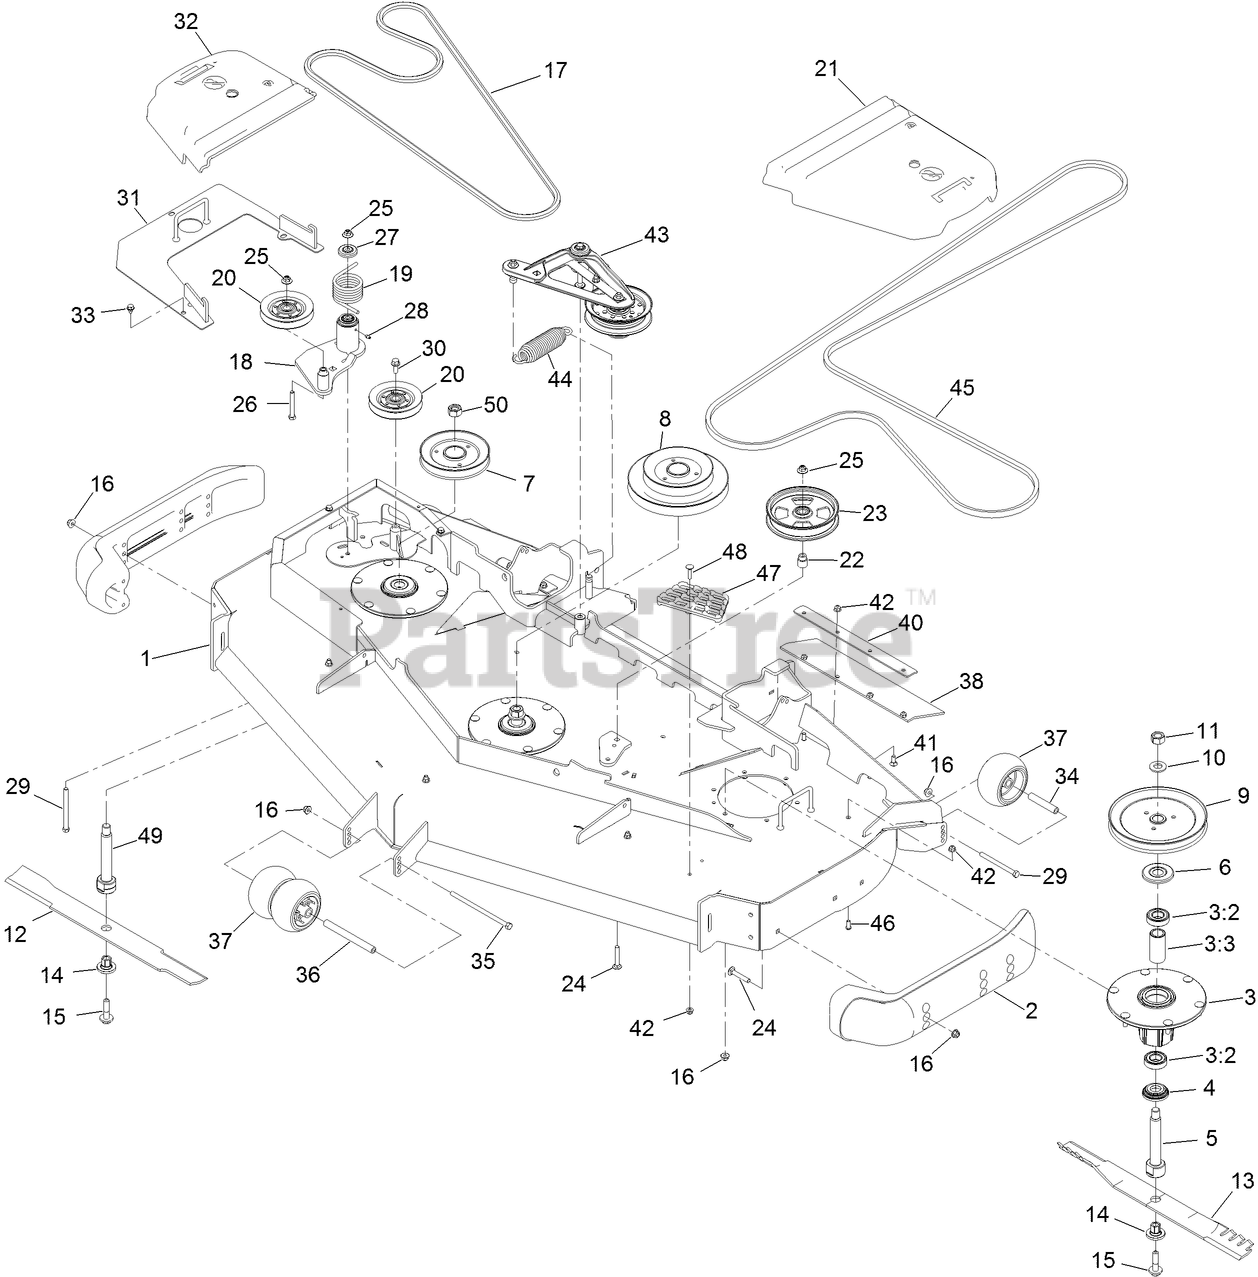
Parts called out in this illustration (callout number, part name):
1	DECK DECAL ASM
2	SKID-BUMPER, DECK
3	SPINDLE ASM
3:2	BEARING-BALL
3:3	SPACER-BEARING
4	GUARD-BOTTOM
5	SHAFT-SPINDLE
6	GUARD-BEARING, TOP
7	SHEAVE, DOUBLE BLADE DRIVE
8	SHEAVE, DOUBLE BLADE DRIVE
9	SHEAVE-DRIVE, BLADE
10	WASHER
11	NUT-HEX
12	BLADE-24.50 CR LOW FLOW
13	BLADE-24.50 ATOMIC
14	BUSHING-HEX
15	SCREW-SEMS
16	NUT-HF, NI
18	IDLER ASM
19	SPRING-TORSION
20	SHEAVE
21	COVER-BELT, LH
22	BUSHING-IDLER
23	PULLEY-IDLER, FLAT
24	SCREW-CARR
25	NUT-FLANGE, NI
26	SCREW-HH
27	GUARD-TOP
28	FITTING-GREASE
29	SCREW-HH
30	SCREW-HHF
31	COVER-REVERSE DRIVE
32	COVER-BELT, RH
33	SCREW
34	TUBE-SPANNER
35	SCREW-HH
36	SPACER-WHEEL
37	ROLLER-SCALP, ANTI
38	GUARD-TIRE
40	SUPPORT-OUTER FLAP
41	SCREW-CARR
42	NUT-HF, NI
43	DECK IDLER ASM
44	SPRING-EXTENSION
46	SCREW-HSBH
47	STEP-DECK
48	SCREW-CARR
49	SHAFT-SPINDLE, INT. HEX LH THD
50	NUT-HEX,LH,LOCK
